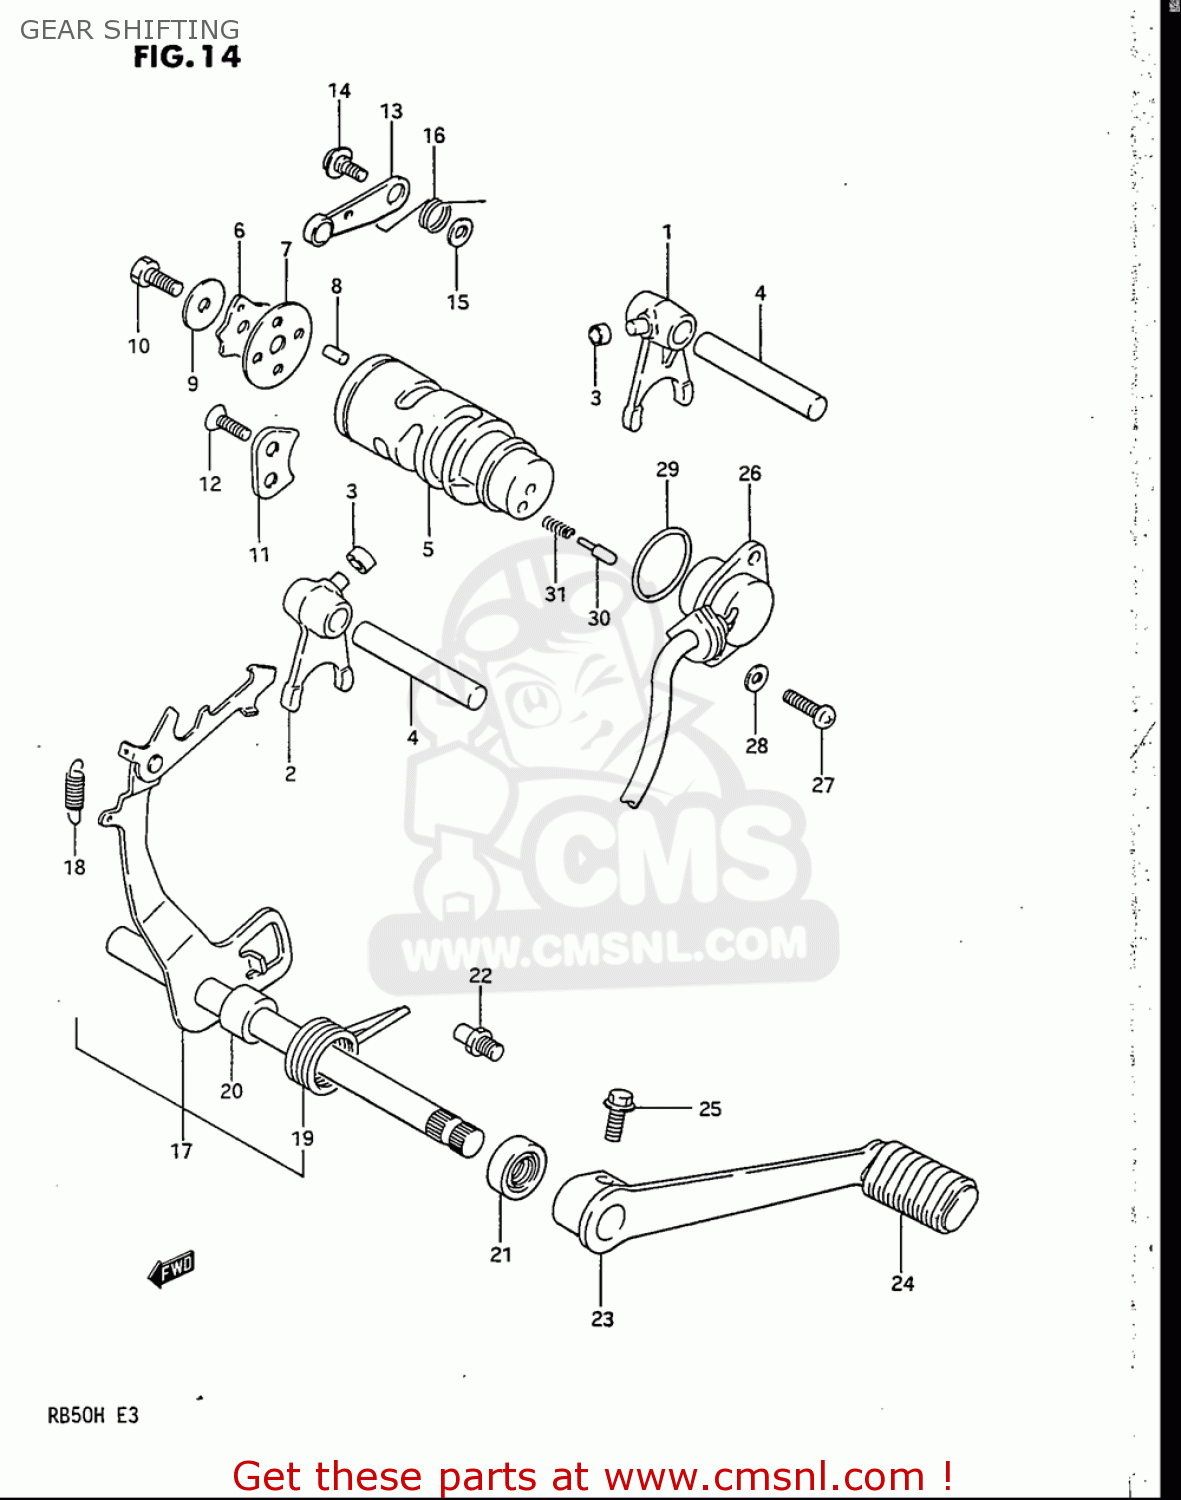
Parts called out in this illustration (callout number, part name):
3	SPACER(6X9.8X6)
8	ROLLER(4X13.8)
10	BOLT
12	SCREW
14	BOLT(6X14.3)
15	WASHER
17	ARM ASSEMBLY,GEAR SHIFT
18	SPRING
19	SPRING
21	SEAL,OIL (12X22X9)
22	STOPPER,GEAR SHIFT ARM
23	LEVER,GEAR SHIFT
24	RUBBER,PEDAL
25	SCREW
27	SCREW
28	WASHER
29	O RING(D:2.4,ID:26.2)
30	PIN(5X15.5)
31	SPRING
